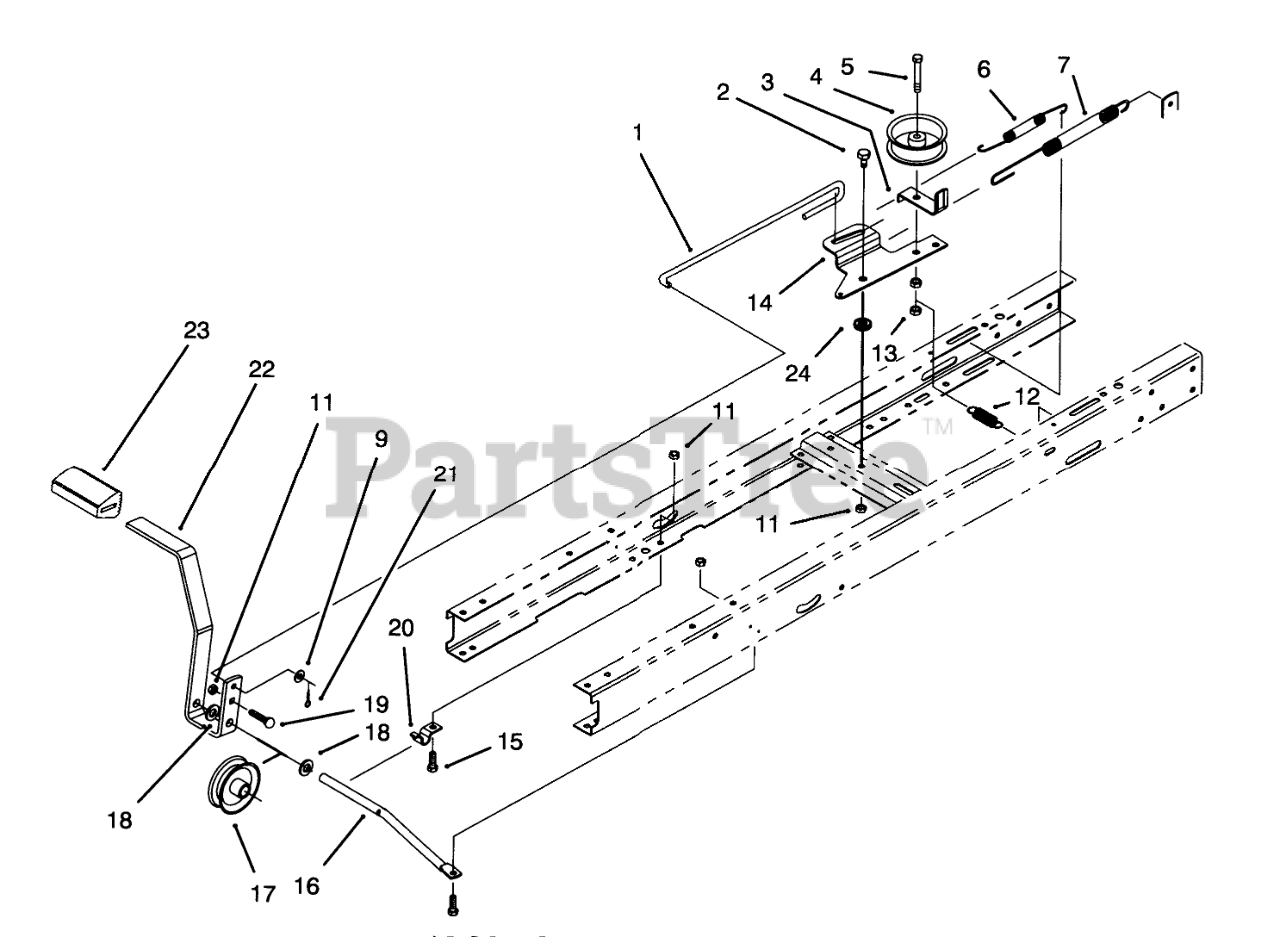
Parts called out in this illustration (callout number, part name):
1	ROD-CLUTCH/BRAKE
2	BOLT-SHOULDER
3	GUIDE-IDLER, BELT
4	Idler Pulley
5	SCREW-HH
6	SPRING-EXTENSION
7	BRAKE SPRING
9	WASHER-PLAIN
11	NUT-LOCK, NI
12	SPRING-EXTENSION
13	NUT-LOCK, NI
14	ARM-IDLER
15	SCREW-HH
16	ROD-PIVOT, PEDAL
17	PULLEY, CABLE
18	WASHER-FLAT
19	SCREW-CARR
20	CLAMP-PIVOT, SHIFT
21	PIN-COTTER
22	Pedal-Clutch/Brake
23	PAD-PEDAL
24	WASHER-PIVOT
